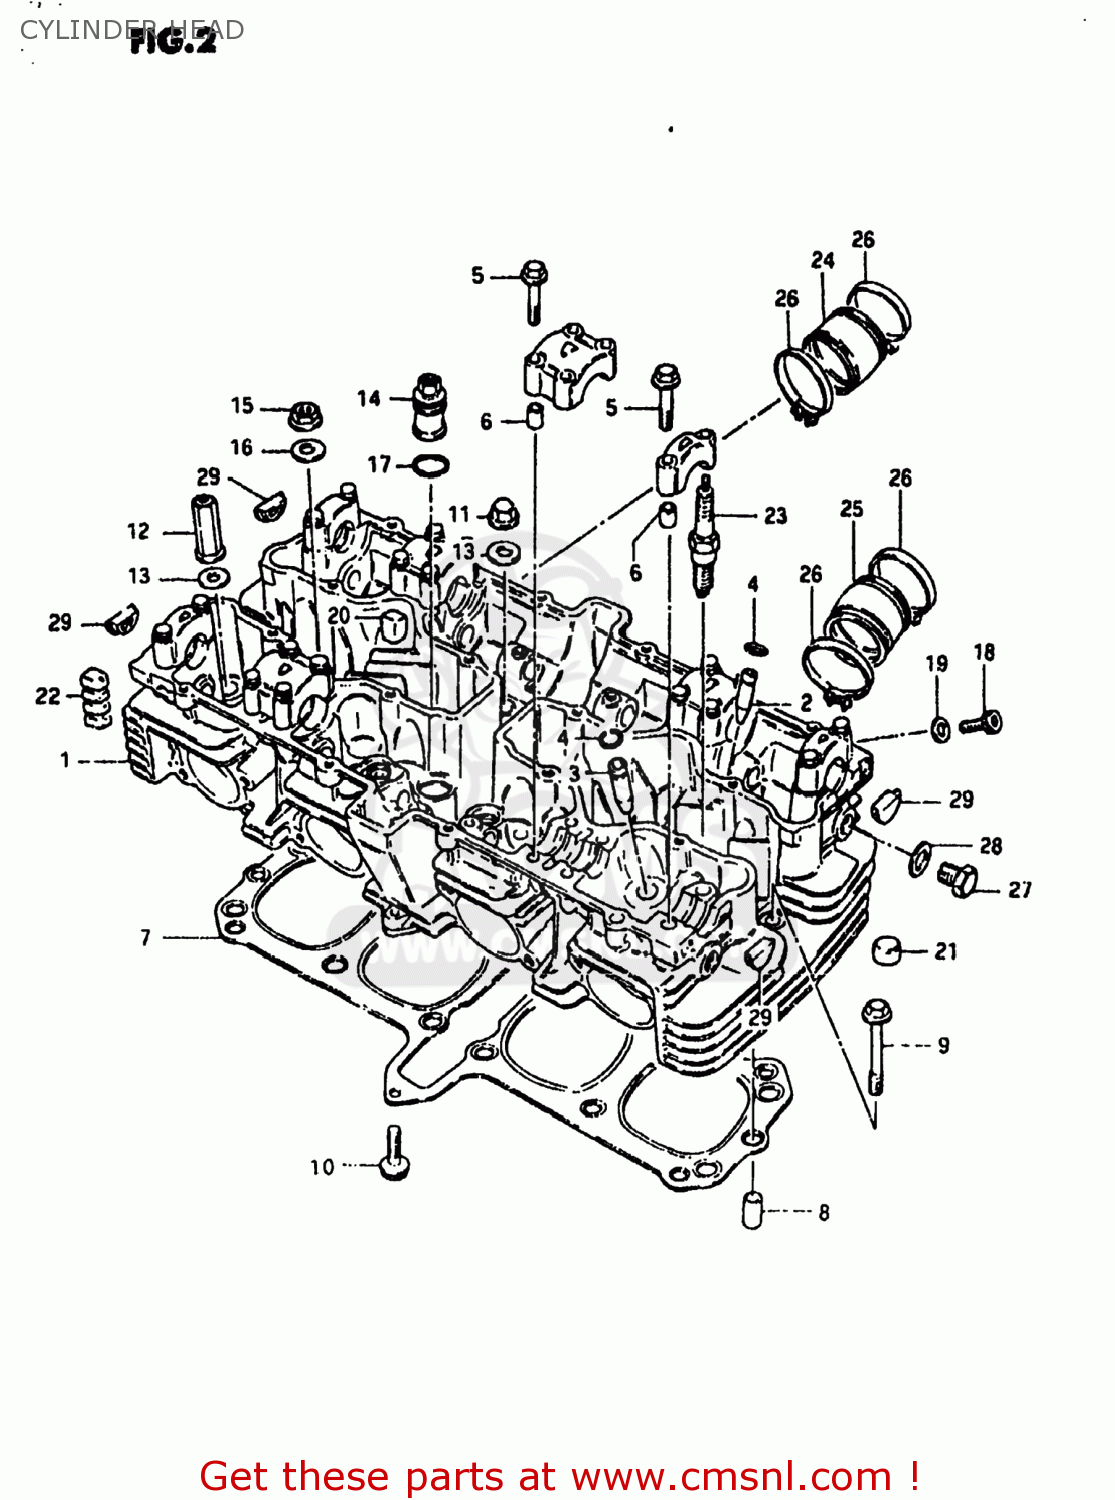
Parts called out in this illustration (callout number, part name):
1	HEAD ASSEMBLY,CYLINDER
2	GUIDE,INTAKE VALVE
3	GUIDE,INTAKE VALVE
4	RING,SNAP
5	BOLT(6X39)
6	PIN(6.2X8X11)
7	GASKET,CYLINDER HEAD (MCA)
8	PIN
9	BOLT
10	BOLT
11	NUT
12	NUT
13	GASKET (NAS)
14	NUT,CYLINDER HEAD SEAL
15	NUT
16	WASHER(10.5X22X2.3)
17	O RING(D:2.4,ID:16.8)
18	BOLT
19	GASKET(5.3X9.3X1.2) (NAS)
20	PAD
21	PAD,CYLINDER HEAD
22	PAD,CYLINDER
23	SPARK PLUG D8EA
24	PIPE,INTAKE,R
25	PIPE,INTAKE
26	CLAMP
27	PLUG (14X12)
28	GASKET(14X19.2X2) (NAS)
29	PLUG
